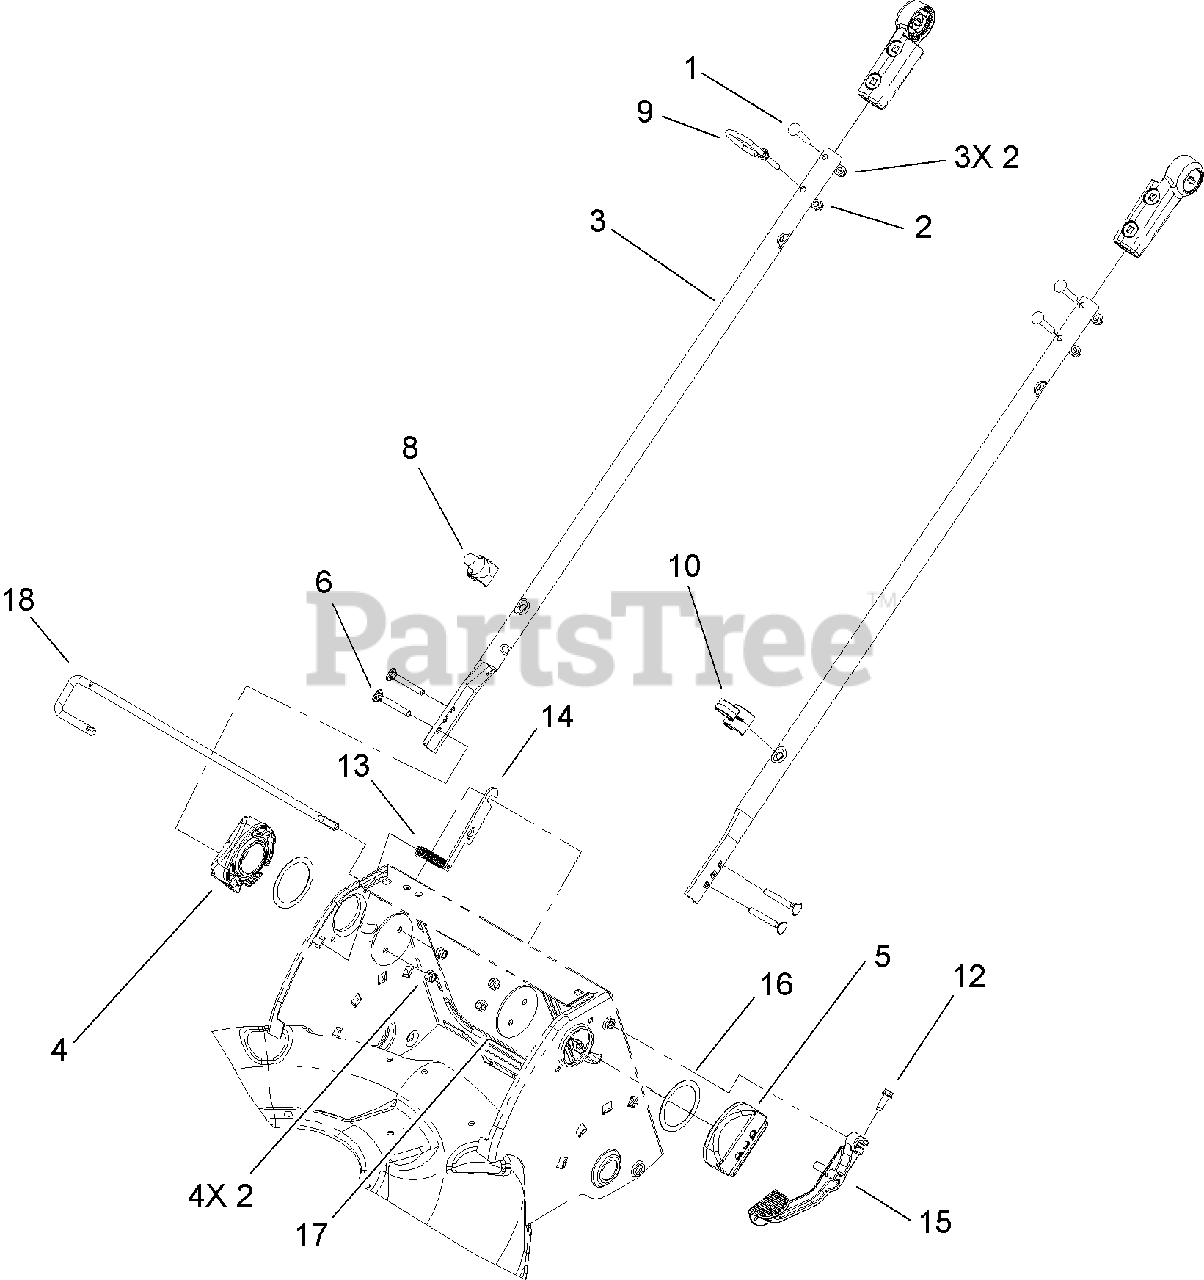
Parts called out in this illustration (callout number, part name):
1	SCREW-CARR
2	NUT-LOCK, NI
4	MOUNT-HANDLE, RH
5	MOUNT-HANDLE, LH
8	GUIDE-ROPE, LOWER
9	GUIDE-ROPE, UPPER
10	Guide-Cable
12	SCREW-HWHTF
13	SPRING-EXTENSION
14	PLATE-RELEASE ROD
15	LEVER-RELEASE
16	WASHER-NYLON
18	HANDLE-ROD, RELEASE
